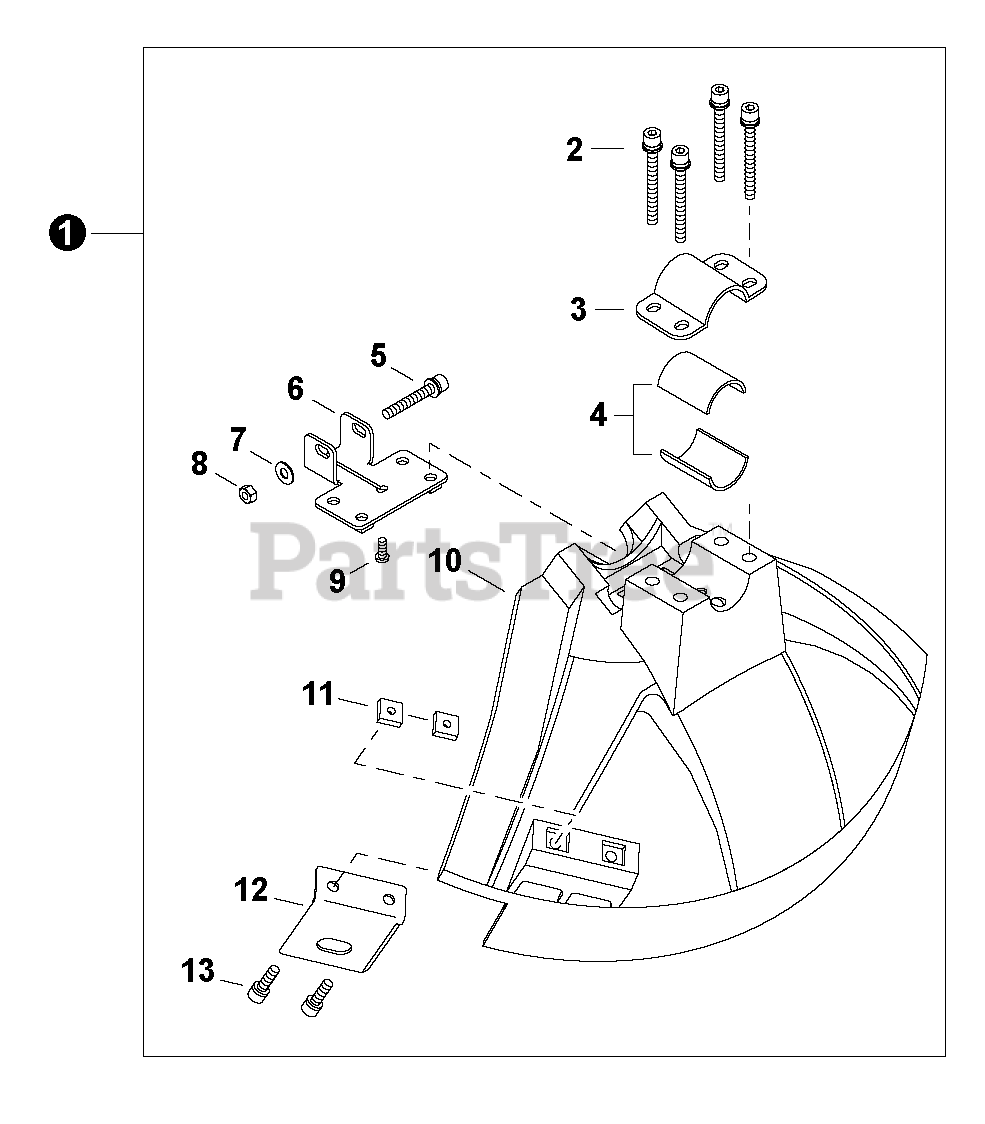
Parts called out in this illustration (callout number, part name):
1	DEBRIS SHIELD ASSY
2	BOLT M5×45
3	CLAMP, UPPER
4	SPACER 26
5	BOLT M6×40
6	PLATE, SHIELD MOUNTING
7	WASHER 6.5×13×1
8	NUT, HEX M6
9	SCREW HILO 4×10
10	SHIELD, DEBRIS
13	BOLT M5×16
